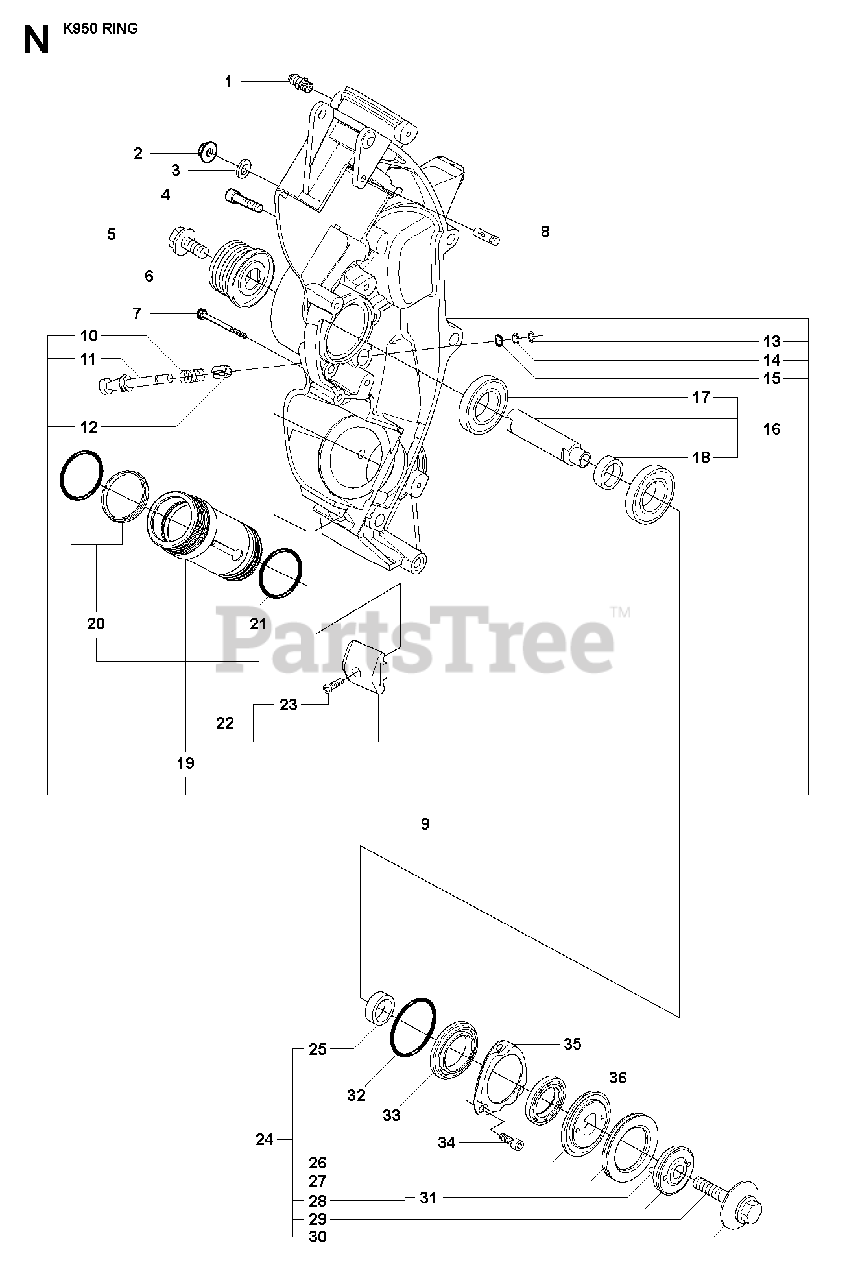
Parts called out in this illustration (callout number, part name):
1	LUBRICATION NIPPLE
17	BALL BEARING
36	SEALING RING
